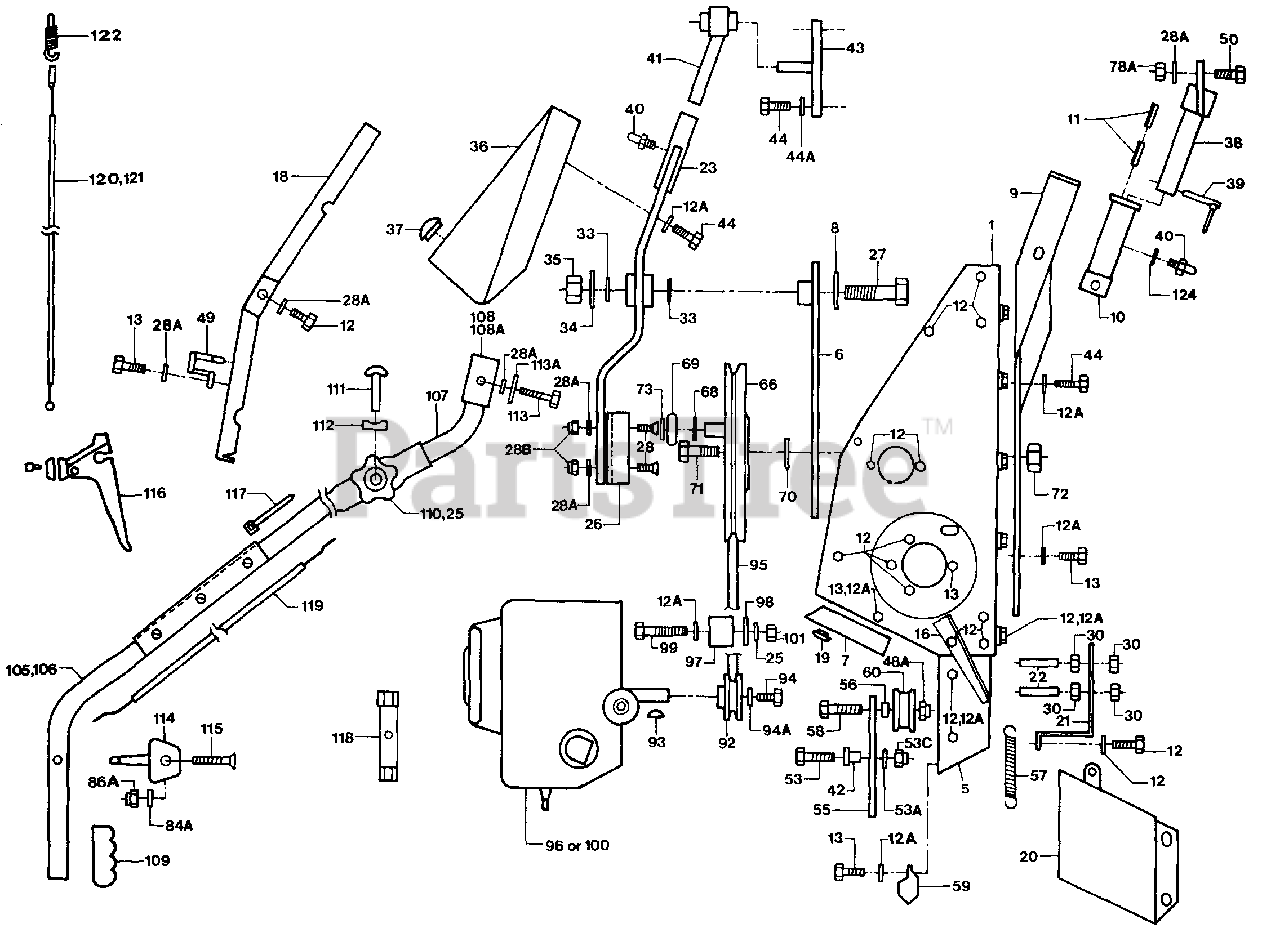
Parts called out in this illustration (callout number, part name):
1	THIS REF. NO. NOT USED
5	Plate-Engine Mount
6	Plate-Bottom Reinforcement
7	Frame Hood-Rear
8	Washer, Drive Arm, Bottom
9	Cutter Bar Weldment
10	Cutter Bar Holder
11	Roll Pin Set-6 x 20
12	Screw-HHM8 x 12
12A	Washer
13	Screw-HHM8 x 16
16	Grass Shield-Wheel-RH
18	Hood w/Logo Decal
19	Plastic Plug
20	Cover-Drive Belt
21	Cover-Cutter Bar Belt
22	Rod-Belt Disengagement
23	Drive Arm Assembly
25	Star Washer
26	Channel-Drive Arm
27	Drive Arm Pivot Bolt M16
28	Screw FHC 90° MS x 30 Class 10.9
28A	Washer
28B	Nylon Nut M8 Class 10.9
33	Snap Ring
34	Washer, Drive Arm, Top
35	Nut-Nylon M16
36	Grass Shield w/Decal
37	Plastic Plug-Grass Shield
38	Mounting Shaft-Cutter Bar
39	Retaining Clip-M8 x 40
40	Grease Fitting-M6 x 100
41	Drive Socket and Bushing
42	Clutch Plate Blade Bushing
43	Mount-Cutter Bar
44	Screw-HHM8 x 20
44A	Washer
48A	Nylon Nut
49	Wheel Drive Cable Protector
50	Screw-M8 x 25
53	Screw-HHM10 x 35
53C	Nut-Nylon-HM10
55	Clutch Plate Blade
56	Bushing-Idler
57	Spring-Blade Engagement
58	Screw-HHM12 x 45
59	Cutter Bar Cable Protector
66	Flywheel Blade w/Bng. Assy.
68	Spacer-Flywheel
69	Convex Bearing
70	Washer-Flywheel
71	Screw-M20-Flywheel
72	Nut-Flywheel
73	Circlip-Flywheel
78A	Nylon Nut
84A	Washer
86A	Nylon Nut
92	Pulley-Cutter Bar
93	Key-Woodruff (Engine Pulley)
94	Screw-3/8-24 HH
95	V -Belt-Cutter Bar
96	Engine-3.5 HP Briggs & Stratton
99	Screw-HHM8 x 70
100	Engine-4.0 HP I.C. Briggs & Stratton
101	Nut-M8
105	Handlebar w/Decals & Grips
106	Upper Handlebars w/Decals & Grips
107	Lower Handlebars
108	Rubber Tube-Handlebar R/H
108A	Rubber Tube-Handlebar L/H
109	Grip-Handlebar
110	Knob-Handlebar
111	Bolt-Handlebar
112	Lock Clamp-Handlebar
113	Screw-HHM8 x 55
113A	Washer
114	Throttle Control w/Decal
115	Screw M6 x 45
116	Handlebar Lever-Control
117	Tie Strap
118	Wrench-Spark Plug
119	Throttle Cable
120	Cable-Cutter Bar
121	Cable-Wheel Drive
122	Spring-Cable-Wheel Drive
124	Washer
